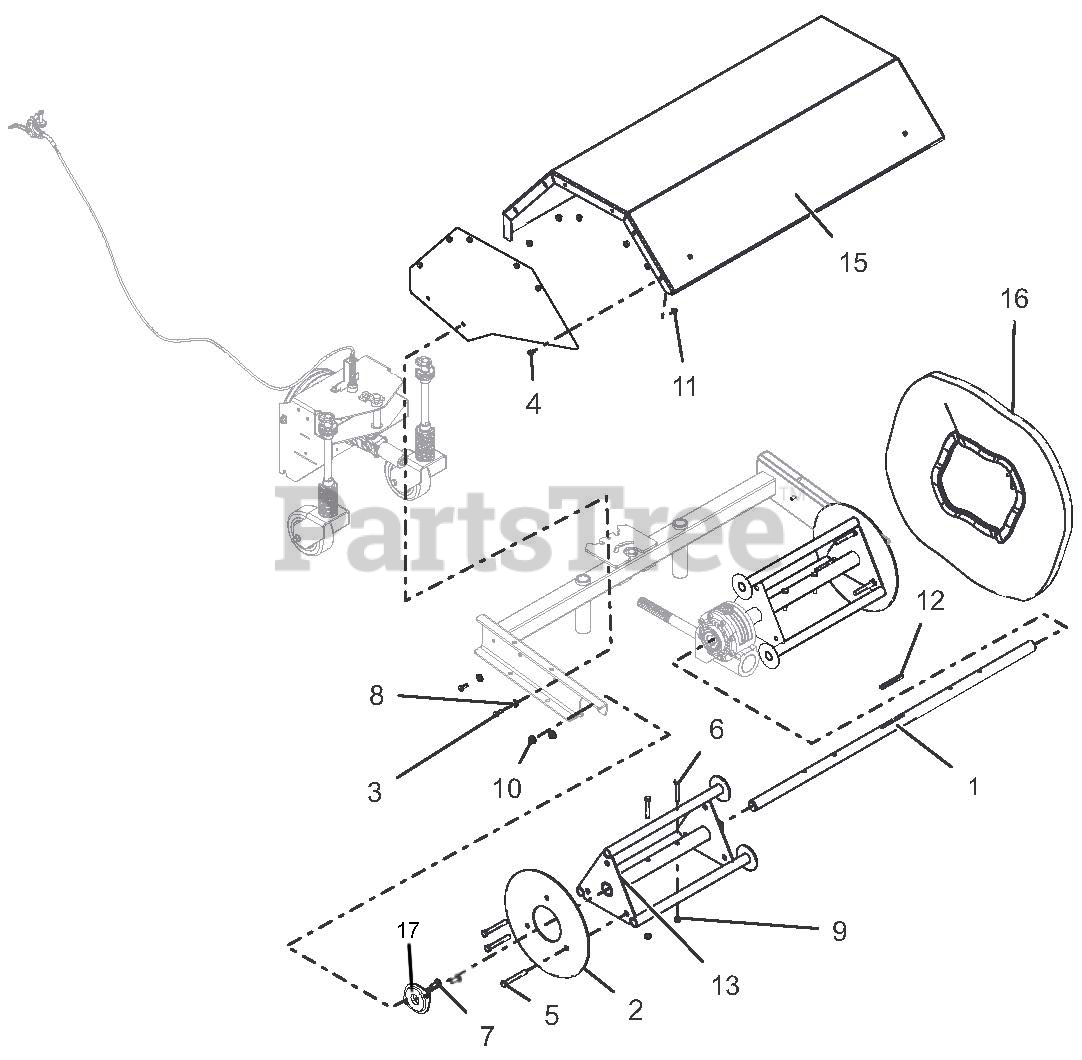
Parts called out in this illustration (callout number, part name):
1	SHAFT, CENTER
2	PLATE, END - RETAINER
3	BLT-HEX .25-20X.75 GR5 YWZC
4	BLT-HEX .25-20X.50 GR5 YWZC
5	BLT-HEX .38-16X3.00 GR5 FTH YWZC
6	BLT-HEX .31-18X2.25 GR5 YWZC
7	BLT-RDHDSQNK .38-16X1.00 G5 YWZC
8	WSHR-FL-STL.312X.734X.065 YWZ
9	NUT-LK-CTR .31-18 YWZC
10	NUT, LK-TOP-FLG .38-16 YWZC
11	NUT, LK-TOP-FLG .25-20 YWZC
12	KEY-SQ .250X.250X3.00
13	BRUSH, DRIVE CORE - SERVICE KIT
15	COVER, TOP - 36" BRUSH W/DECALS
16	BRISTLE REPLACEMENT - SET OF 18
17	BEARING, 2 BOLT FLANGE 1-1/8 ID
